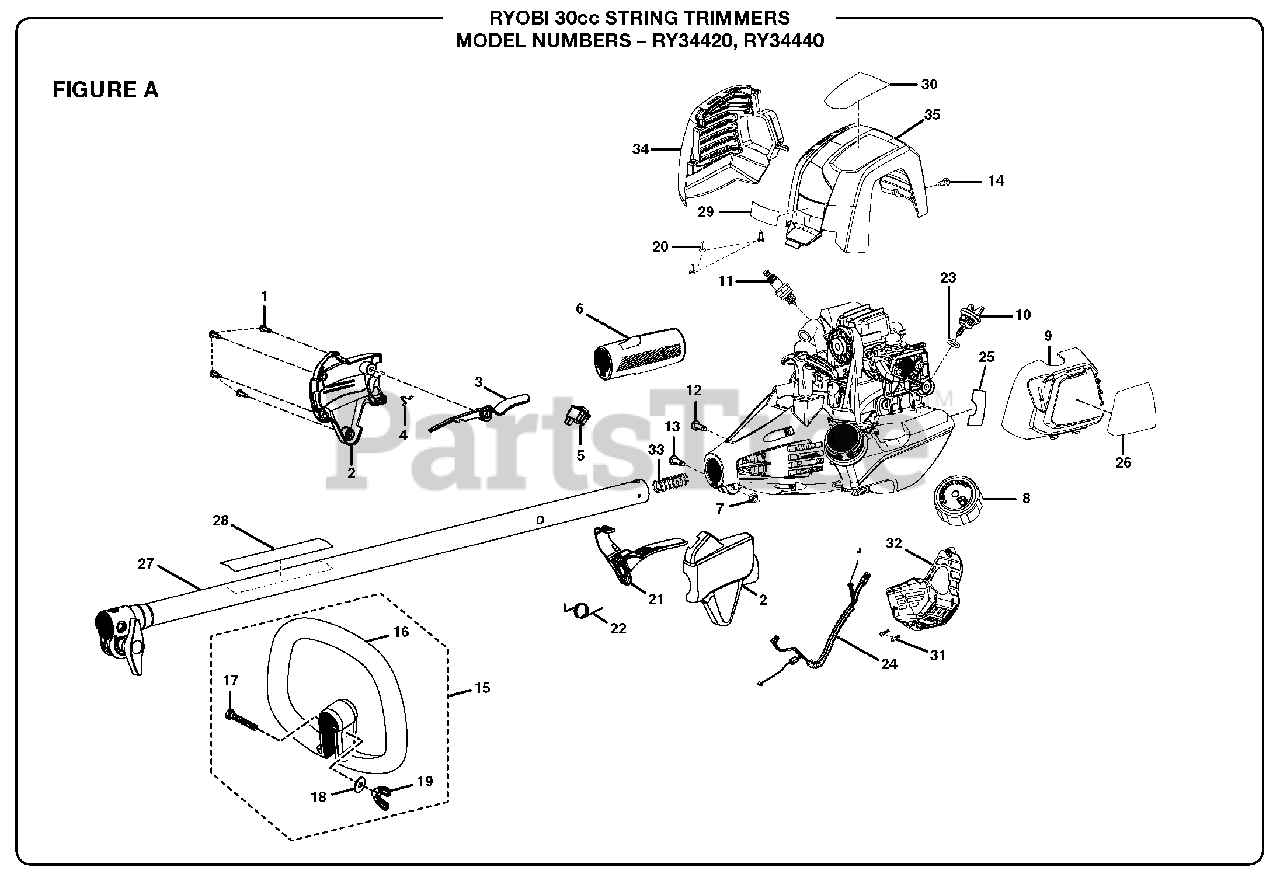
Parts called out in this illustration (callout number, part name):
1	Screw (M4 x 20 mm)
2	Control Handle Assembly
3	Trigger Lock
4	Strap Hanger
5	Switch (Momentary Contact)
6	Rear Handle
7	Hex Nut (M6.3 x 1)
8	Fuel Cap Assembly
9	Air Box Cover
10	Oil Cap/Dipstick
11	Spark Plug (Champion RZ7C)
12	Screw (#8-16 x 5/16 in.)
13	Bolt (M6 x 1 x 30 mm)
14	Screw (M5 x 11 mm)
15	Front Handle Assembly
16	Front Handle
17	Bolt (1/4-20 x 40 mm)
18	Washer (1/4 in.)
19	Wing Nut (1/4-20)
20	Screw (M4 x 12 mm)
21	Throttle Trigger
22	Throttle Trigger Spring
24	Throttle Cable and Lead Assembly
25	Hot Surface Label
26	Starting Label
27	Upper Boom Assembly
28	Warning Label
29	Logo Label
30	C430 Label (RY34420)
30	S430 Label (RY34440)
31	Screw (#6-19 x 1/2 in.)
32	CE Cover (Bottom Cover)
33	Compression Spring
34	Muffler Housing
35	Top Cover
35	Operator's Manual (960646002)
